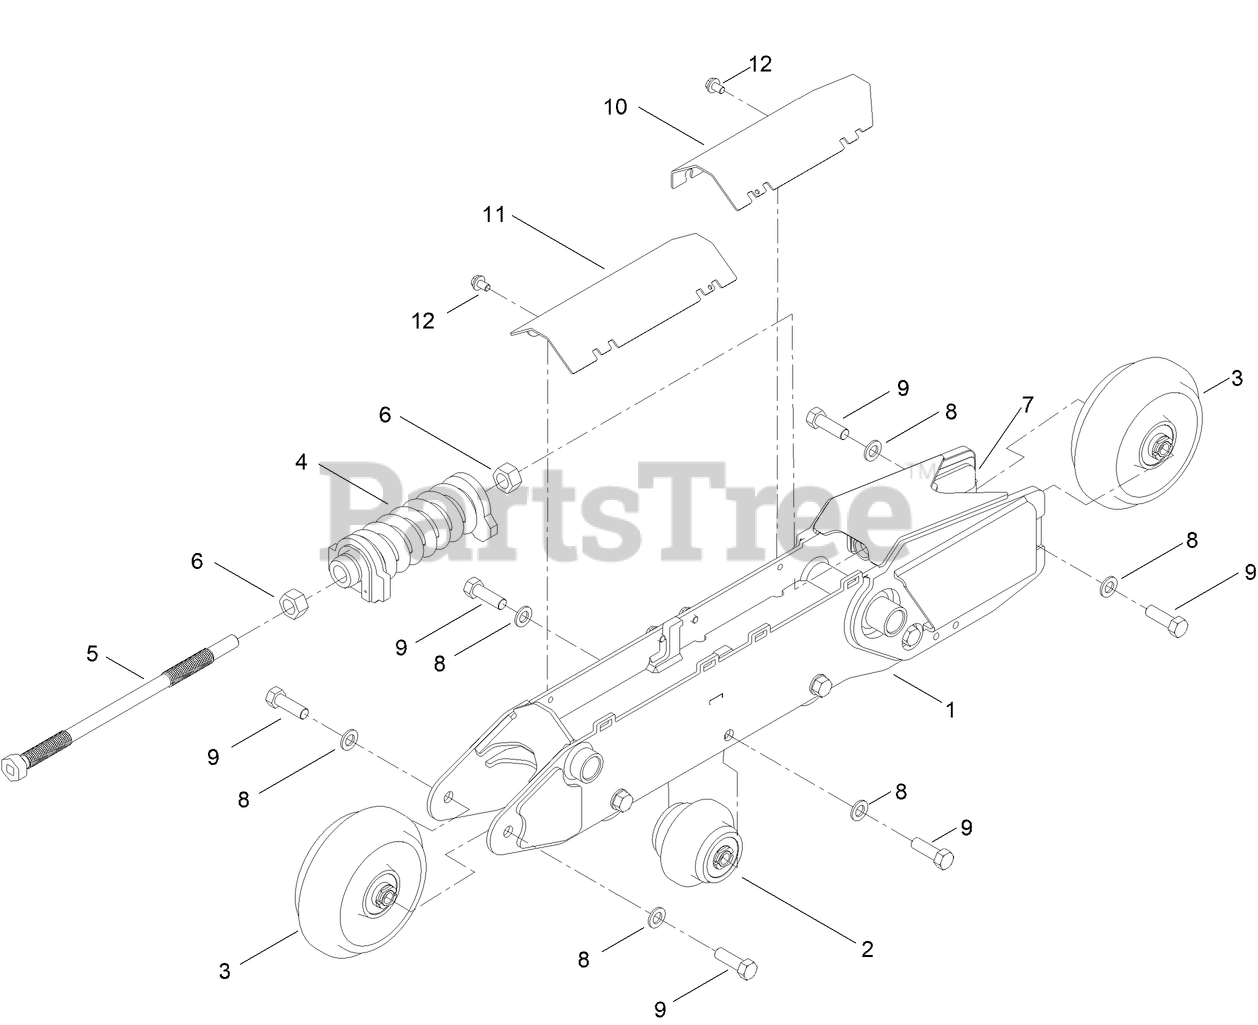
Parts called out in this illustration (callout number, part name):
1	FRAME-TRACK LH
2	WHEEL-ASM CAMSO
3	WHEEL-ASM TENSIONER
4	KIT-SPRING TENSION
5	SCREW-TENSIONER
6	NUT-HEX
7	YOKE-TENSIONER
8	WASHER
9	SCREW-HH
10	PLATE-COVER LH
11	PLATE-COVER LH
12	SCREW-HHF
